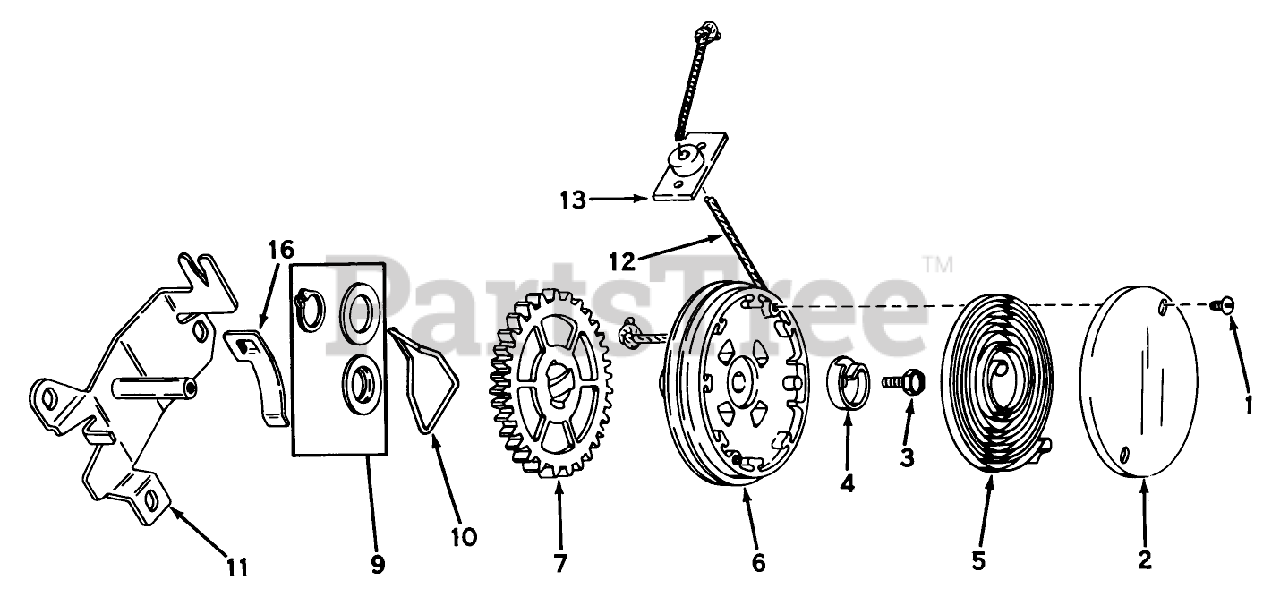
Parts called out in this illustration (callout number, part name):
1	Screw, Cover
2	Cover, Spring
3	Screw, Hex Washer Head
4	Hub Spring
5	Spring, Rewind
6	Pulley Assy. (Incl. No. 9)
9	Kit, Thrust Wash. Snap Rg.
10	Brake
11	Bracket Assy. Mounting
12	Rope, Starter
13	Bracket Assy.
16	Clip Rope
